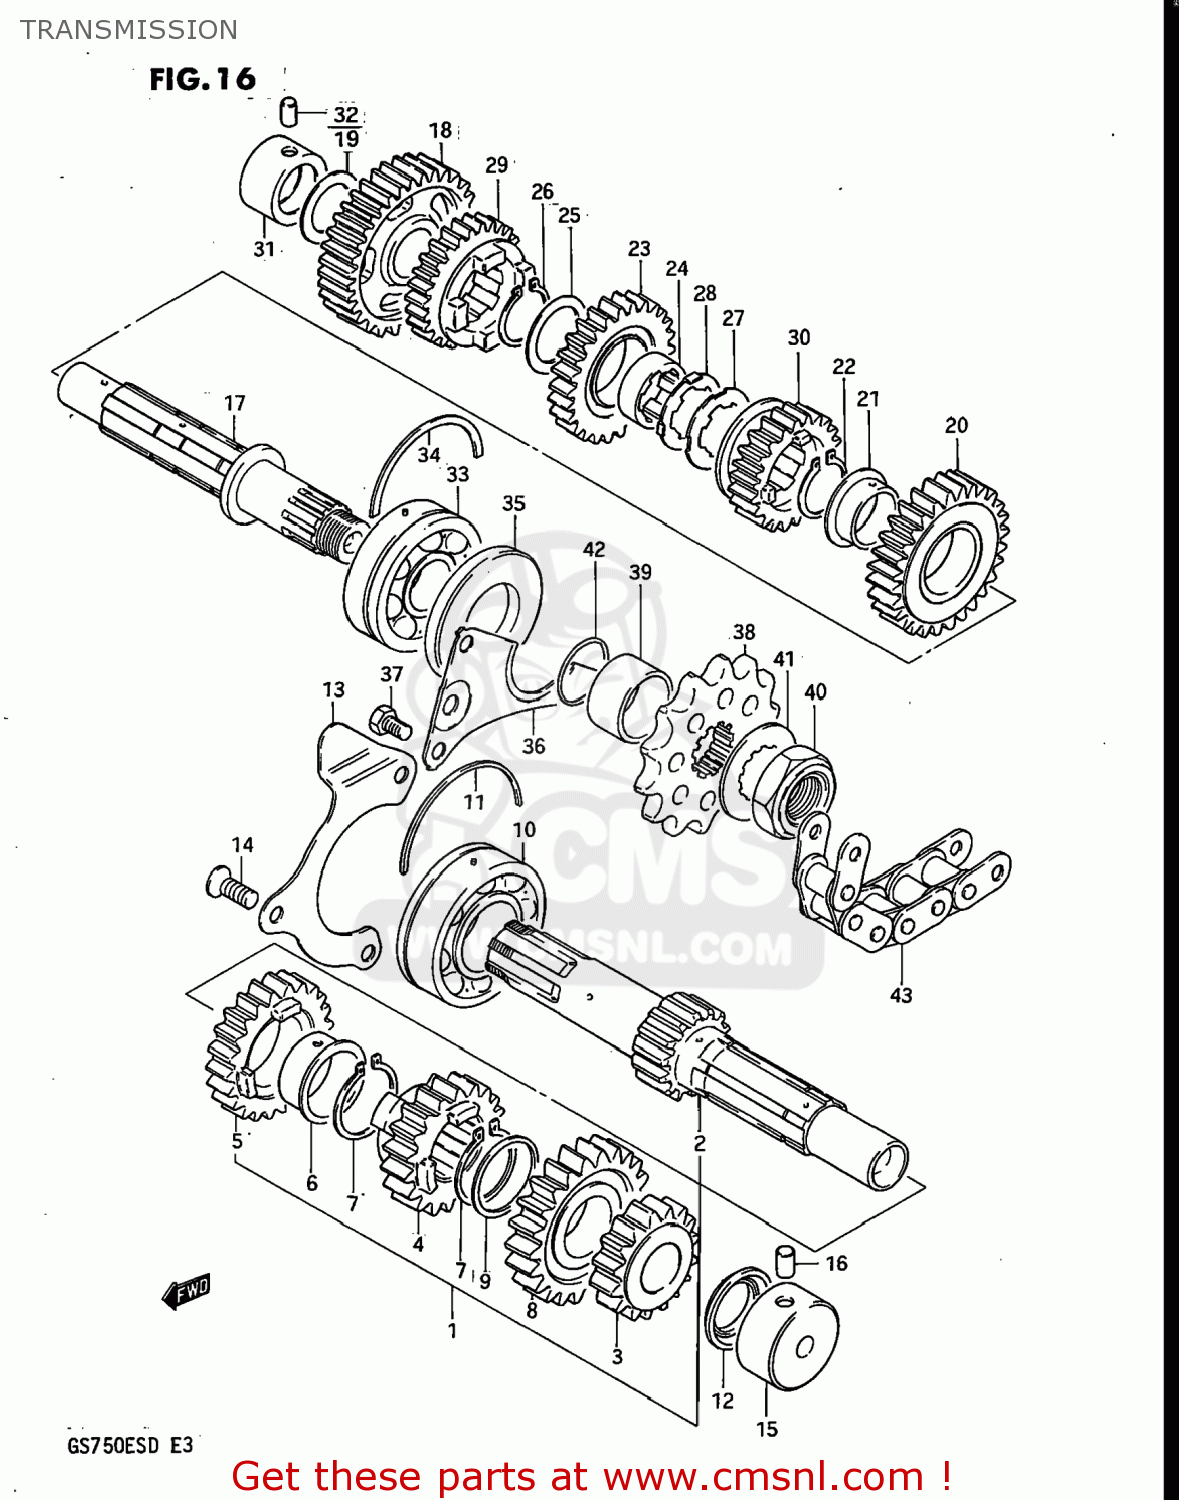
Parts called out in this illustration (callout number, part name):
1	SHAFT,COUNTER
2	SHAFT,COUNTER
3	GEAR,SECOND DRIVE
4	GEAR,THIRD DRIVE
5	GEAR,FOURTH DRIVE
6	BUSHING
7	RING,SNAP
8	GEAR,FIFTH DRIVE (NT:23)
9	WASHER,LOCK
10	BEARING(25X62X17)
11	C-RING
12	SEAL,OIL(20X31.2X2.7)
13	PLATE,COUNTERSHAFT BEARING
14	SCREW
15	BEARING(20X34X17.5)
16	PIN
17	SHAFT,DRIVE
18	GEAR,1ST DRIVEN(NT:35)
19	WASHER
20	GEAR,2ND DRIVEN(NT:28)
21	BUSH(28X32X2)
22	CIRCLIP
23	GEAR,THIRD DRIVEN
24	BUSH,3RD DRIVEN GEAR
25	WASHER,LOCK
26	CIRCLIP
27	WASHER,LOCK
28	WASHER
29	GEAR,FOURTH DRIVEN
30	GEAR,5TH DRIVEN(NT:22)
31	BEARING(20X34X20)
32	PIN
33	BEARING(25X62X17)
34	C-RING
35	SEAL,OIL(33X62X7)
36	PLATE,DRIVESHAFT OIL
37	BOLT
38	SPROCKET,ENGINE
39	SPACER (25X33X20.1)
40	NUT
41	WASHER
42	O RING(D:1,ID:24.5)
43	CHAIN ASSEMBLY,DRIVE
